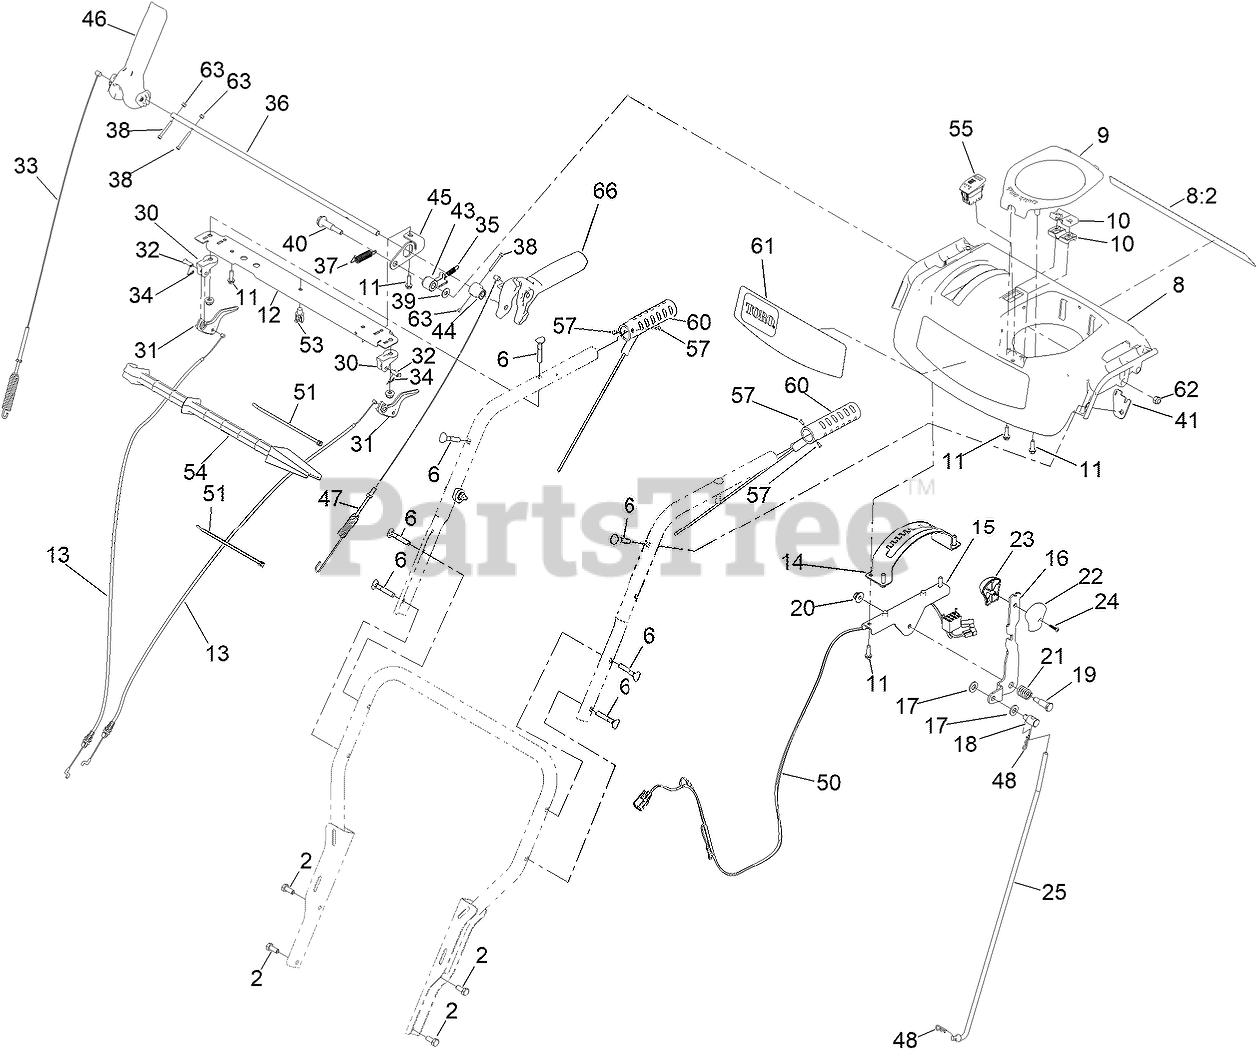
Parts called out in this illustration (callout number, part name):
2	SCREW-HH
6	SCREW-HANDLE
8	PANEL-CONTROL, ASSEMBLY
8:2	DECAL-SAFETY
9	COVER-QUICKSTICK
10	SUPPORT-ROD
11	SCREW-PLASTITE, HWH
12	BRACE-CONSOLE
13	CABLE-CLUTCH
14	GATE-SHIFT
15	BRACKET-SHIFT
16	SELECTOR-SPEED
17	WASHER-FLAT
18	TRUNNION-ROD
19	SCREW-SHOULDER, HH
20	NUT-HF
21	SPRING-COMPRESSION
22	KNOB-SHIFT, LH
23	KNOB-SHIFT, RH
24	SCREW-PPH
25	ROD-SHIFT
30	MOUNT-LEVER, CLUTCH
31	LEVER-CLUTCH
32	PIN-CLEVIS
33	CABLE-AUGER
34	PIN-HAIR
35	SPRING-LOCKOUT, HANDLE
36	ROD-LOCKOUT
37	SPRING-RETURN, LEVER
38	SCREW-HSH,SPL
39	WASHER-FLAT
40	SCREW-SHOULDER
41	PLATE-SPRING
43	LATCH, LOCKOUT
44	CAM-LOCKOUT
45	BRACKET-INTERLOCK
46	LEVER-CONTROL
47	CABLE-TRACTION
48	PIN-HAIR
50	HARNESS-WIRE, LED AND HAND WARMERS
51	TIE-CABLE
53	CLIP-TIE
54	STICK-CLEANOUT
55	SWITCH-ROCKER, ON-NONE-OFF (HEATER)
57	RIVET-POP
60	RED HEATED GRIP
61	DECAL-CONSOLE
62	NUT-HEX
63	NUT-LOCK ROHS
66	LEVER-CONTROL
